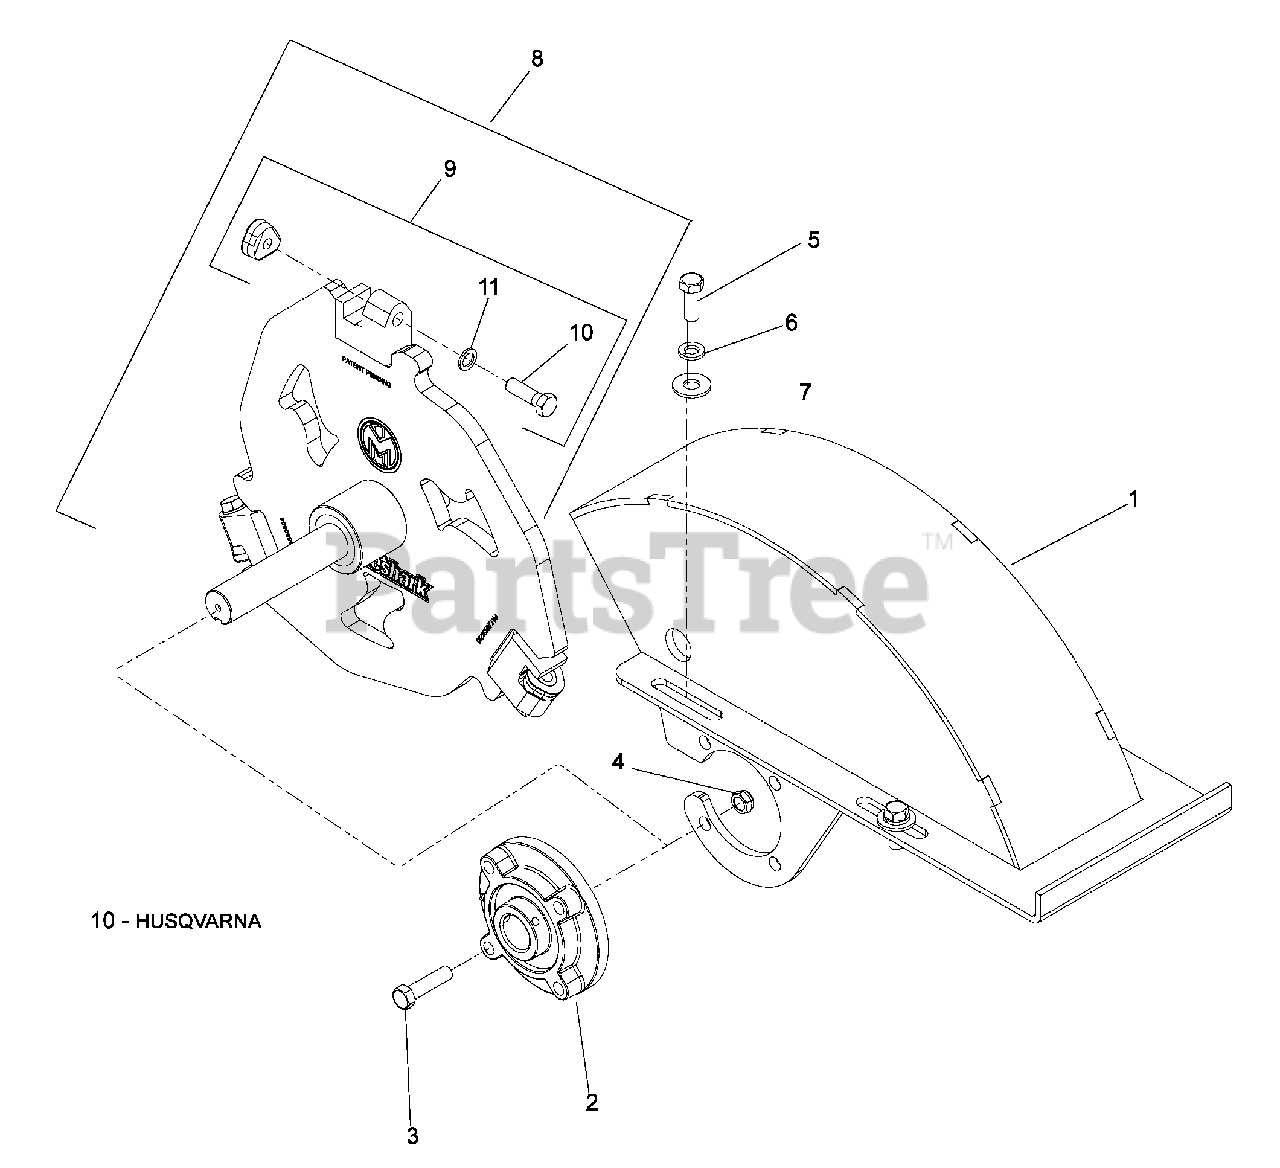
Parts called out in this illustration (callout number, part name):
1	SHROUD KIT w/DECAL and Items 5-7
2	BEARING
3	HCS 3/8-16 x 1½
4	NUT, 3/8-16 JAM NYLOC
5	HCS 3/8-16 x 1
6	WASHER 3/8 SPLIT LK
7	WASHER 3/8 FLAT STD
8	WHEEL w/TEETH, BOLTS, WASHERS
9	KIT, TOOTH
10	HCS 3/8-16 x 1¼
11	WASHER, 3/8 SPRING
